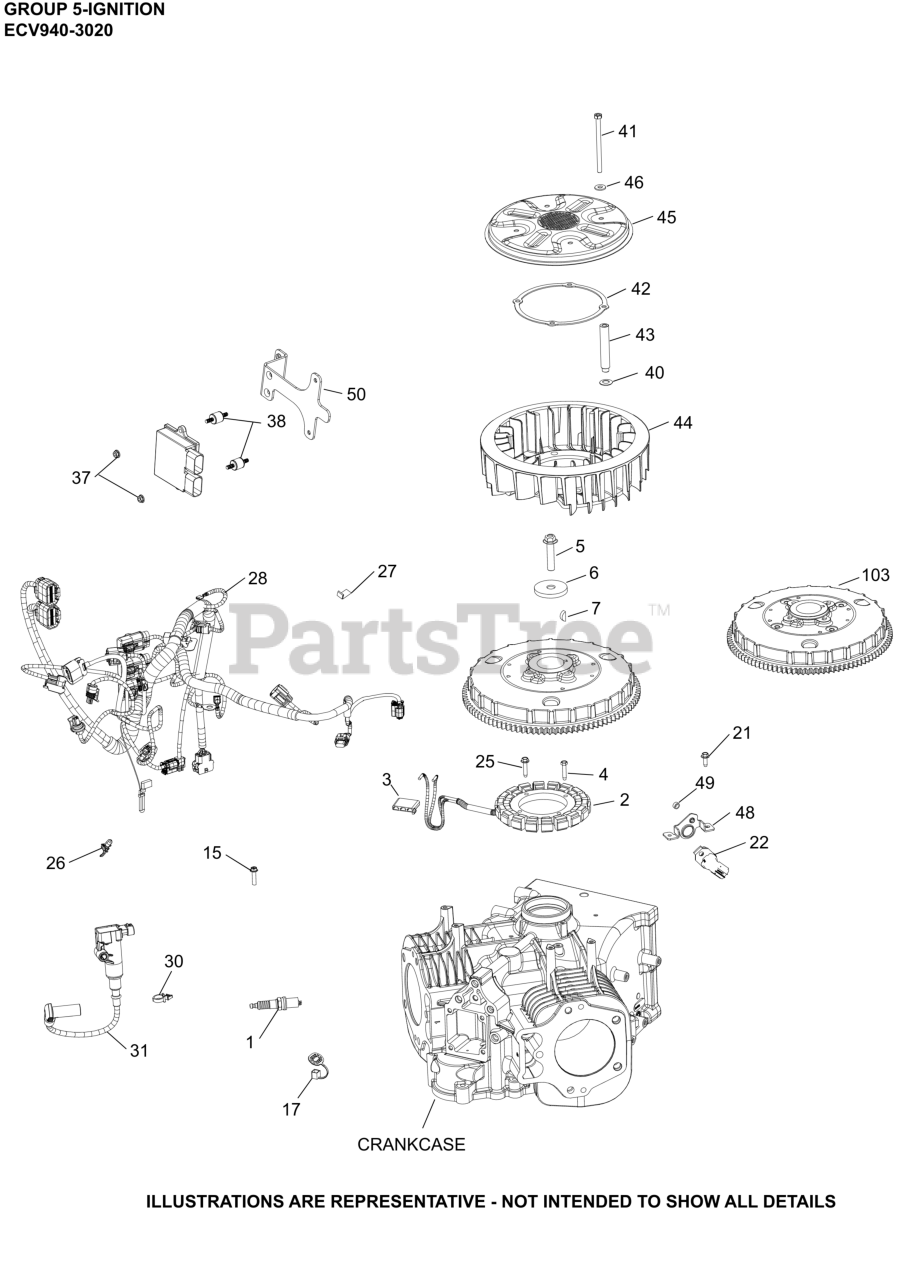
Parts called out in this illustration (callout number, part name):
1	PLUG, SPARK
2	KIT, 15 / 20 AMP STATOR
3	CONNECTOR
4	SCREW, THREAD FORMING
5	SCREW, HEX FLANGE
6	WASHER, FLAT 13/32"
7	KEY, 3/16" X 5/8"
15	SCREW, HEX FLANGE HI-LO
17	CAP, CONNECTOR
21	SCREW, THREAD FORMING
22	SENSOR, SPEED
25	SCREW, THREAD FORMING
26	TIE, WIRE
27	CLIP, BLOWER HOUSING
28	HARNESS, WIRING ASSEMBLY - EFI
31	COIL, IGNITION - EFI
37	NUT, FLG M5X.8
38	ISOLATOR, VIBRATION STUD
40	WASHER, SPRING 10 MM
41	SCREW, HEX HEAD
42	RING, SUPPORT
43	SPACER, GRASS SCREEN
45	SCREEN, GRASS
46	WASHER, FLAT 1/4" (O.D. 5/8")
48	BRACKET, CRANK SENSOR
50	BRACKET, ECU MOUNTING - VERTICAL
103	FLYWHEEL, ASSEMBLY
NI	REGULATOR, RECTIFIER (20-30AMP,FW W/OVP)
